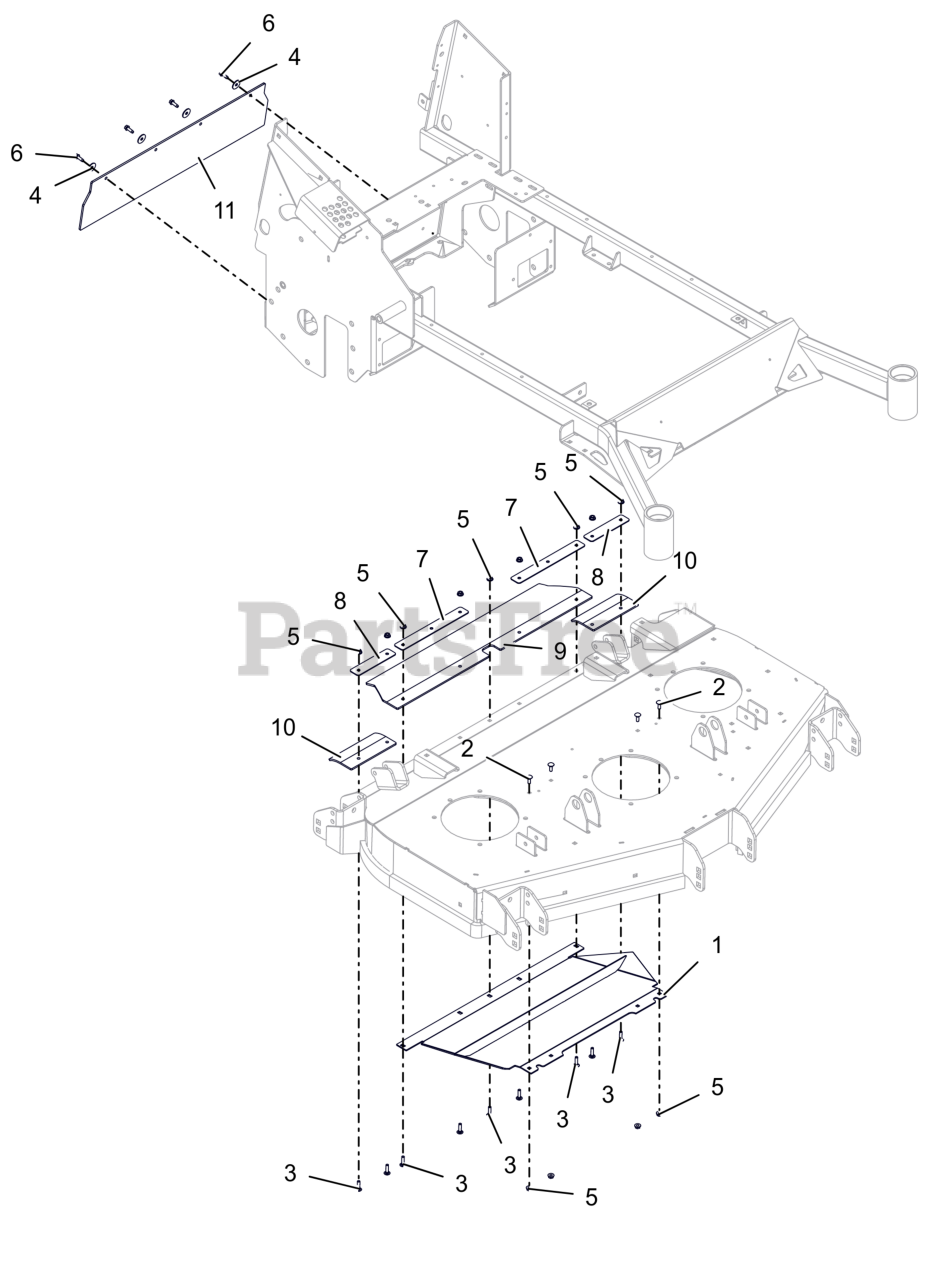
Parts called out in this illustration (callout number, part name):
1	WLDMT, DEFLECTOR BAFFLE (ORANGE)
2	BLT, RHSN .25-20X.750 G5 ZCC
3	BLT, RHSN .25-20X1.00 G5 ZCC
4	WSHR,FLT .281X1.000X.063 ZCC
5	NUT-LK-CTR-FLG .25-20 ZC120
6	SCR,TAP .25-20X.75 HWH TR ZCC
7	PLATE, CHUTE MTG (BLACK)
8	PLATE, 52" TIRE CHUTE MTG (BLACK)
9	CHUTE, REAR DISCHARGE
10	FLAP, REAR DISCHARGE 48" TIRE
11	CHUTE, REAR DISCHARGE
